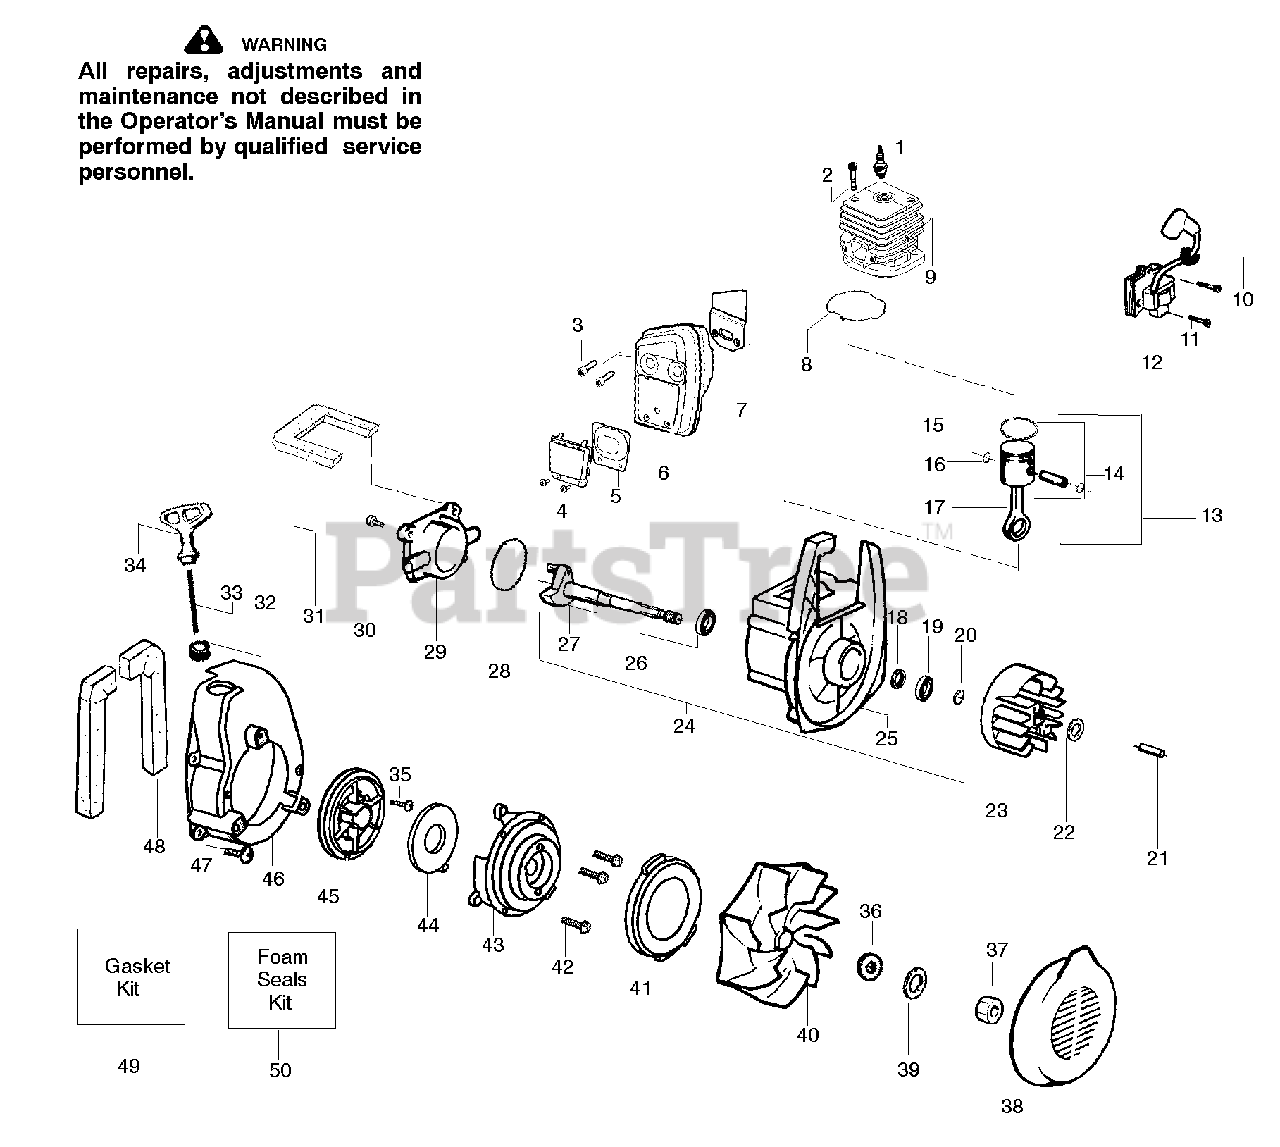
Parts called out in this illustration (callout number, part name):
1	Spark Plug (RCJ-6Y)
3	Screw-Muffler-Internal
5	Kit-Spark Screen
6	Kit-Muffler
7	Gasket-Baffle (kit)
8	Gasket-Cylinder (kit)
10	Grommet-Ign. Module
11	Screw-Ignition Module
12	Ignition Module
13	Kit-Piston/Rod
14	Kit-Piston
15	Piston Ring
16	Retainer-Piston Pin
17	Assy-Connecting Rod
18	Seal-Crankshaft
19	Bearing-Outer
20	Retainer Ring-C'chaft
21	Spacer-Flywheel
23	Assy-Flywheel
24	Assy-Crankcase/Crank shaft
25	Assy-Crankcase
26	Bearing-Inner
27	Assy-Crankshaft
28	O-ring-C/case (kit)
29	Cover-Crankcase
30	Screw
31	Foam-219mm (kit)
32	Eyelet-Flange
33	Kit-Rope
34	Handle-Starter
36	Washer-Belleville
40	Kit-Impeller Assy.
43	Housing-Pulley
44	Spring-Starter
45	Kit-Starter Pulley
47	Screw
48	Foam-182mm (kit)
49	Kit-Gasket
50	Kit-Foam Seals
